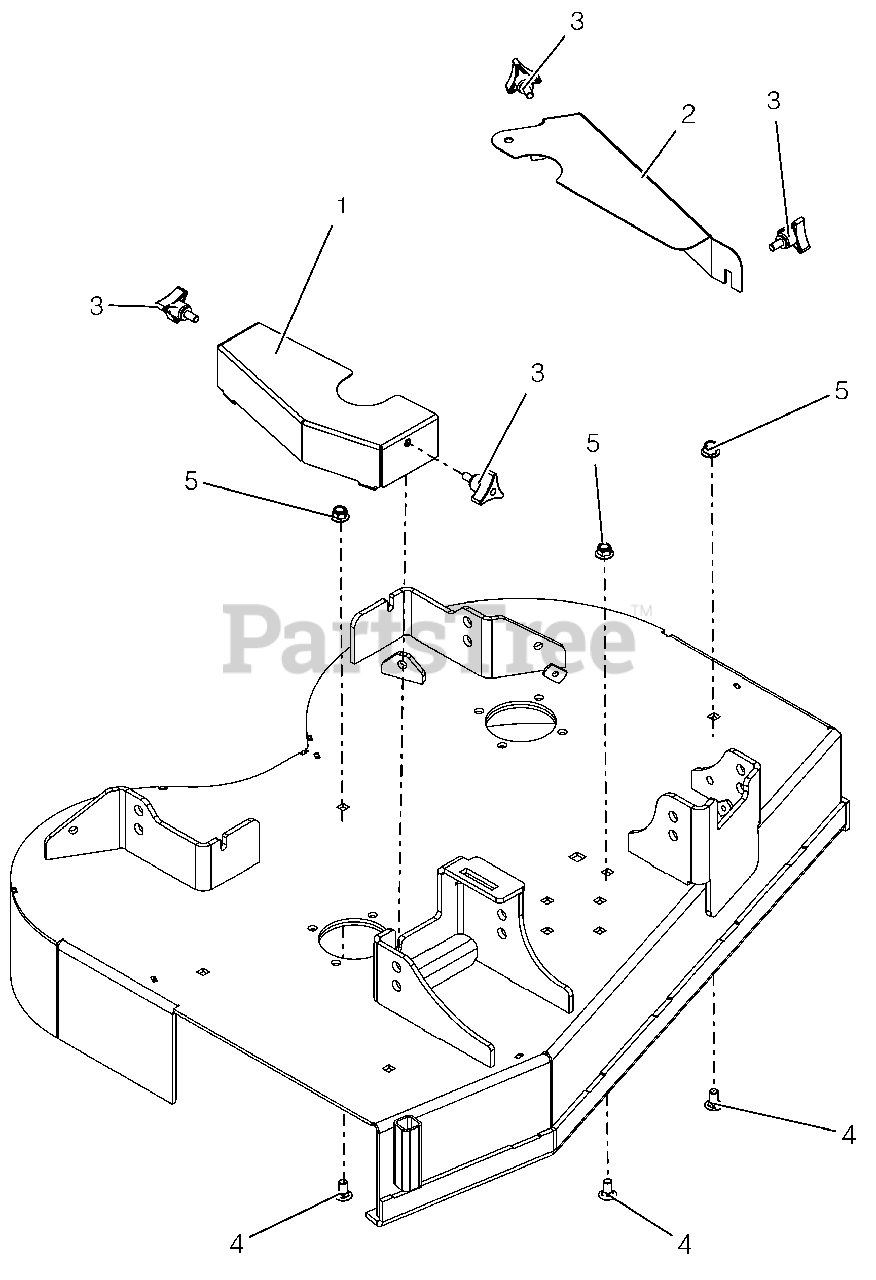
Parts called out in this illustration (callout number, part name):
1	GUARD, RH SPINDLE
2	GUARD, LH SPINDLE
3	KNOB,WING STUD 5/16-18 X .75
4	@BLT-RDHDSQNK .38-16X.75 G5YZ
5	@NUT-LK-NYL-FLG .38-16 YWZC
